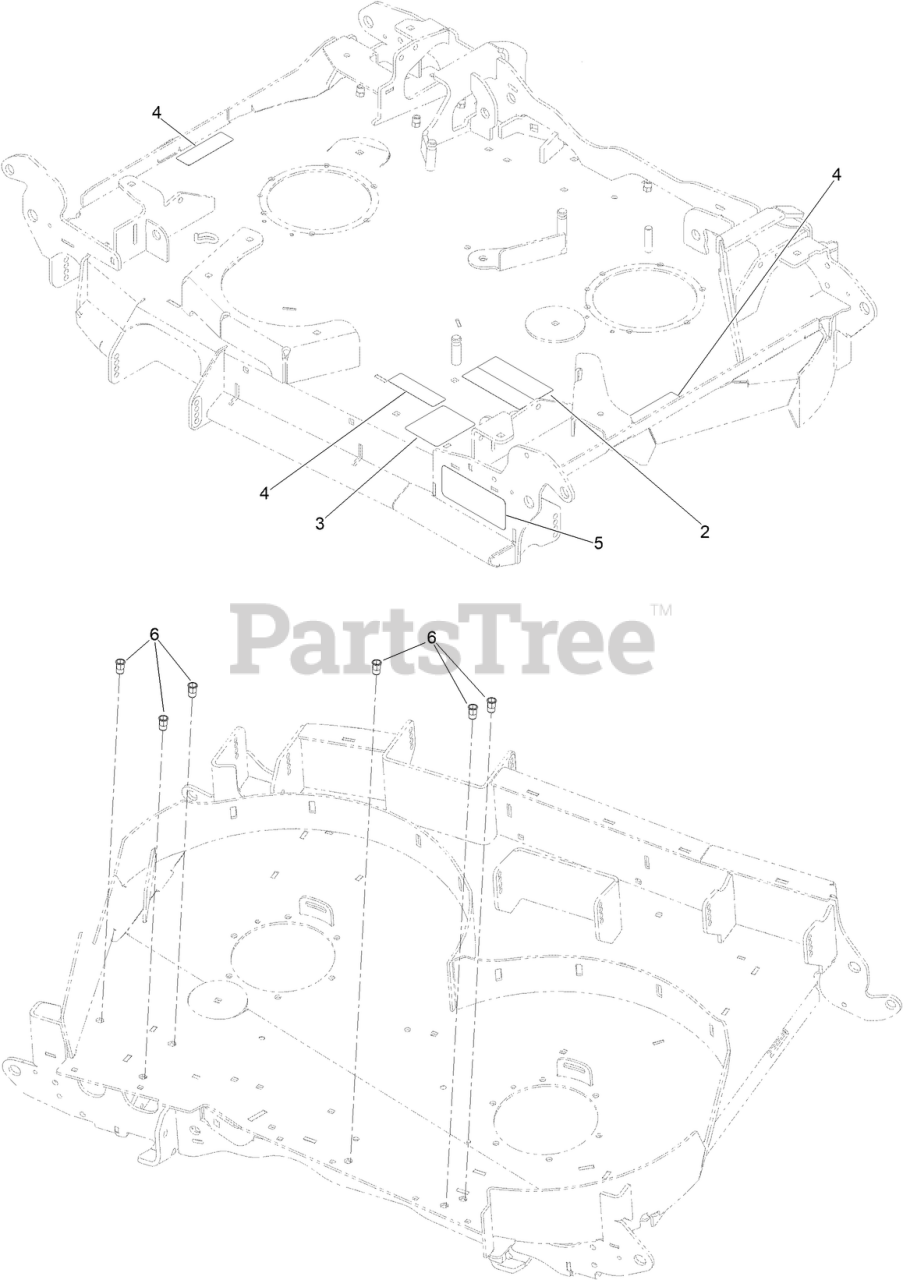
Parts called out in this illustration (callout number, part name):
2	DECAL-DECK BELT ROUTING
3	DECAL-ROLLER, ANTI-SCALP
4	DECAL-COVER, MISSING
6	NUT-CLINCH,HEX
